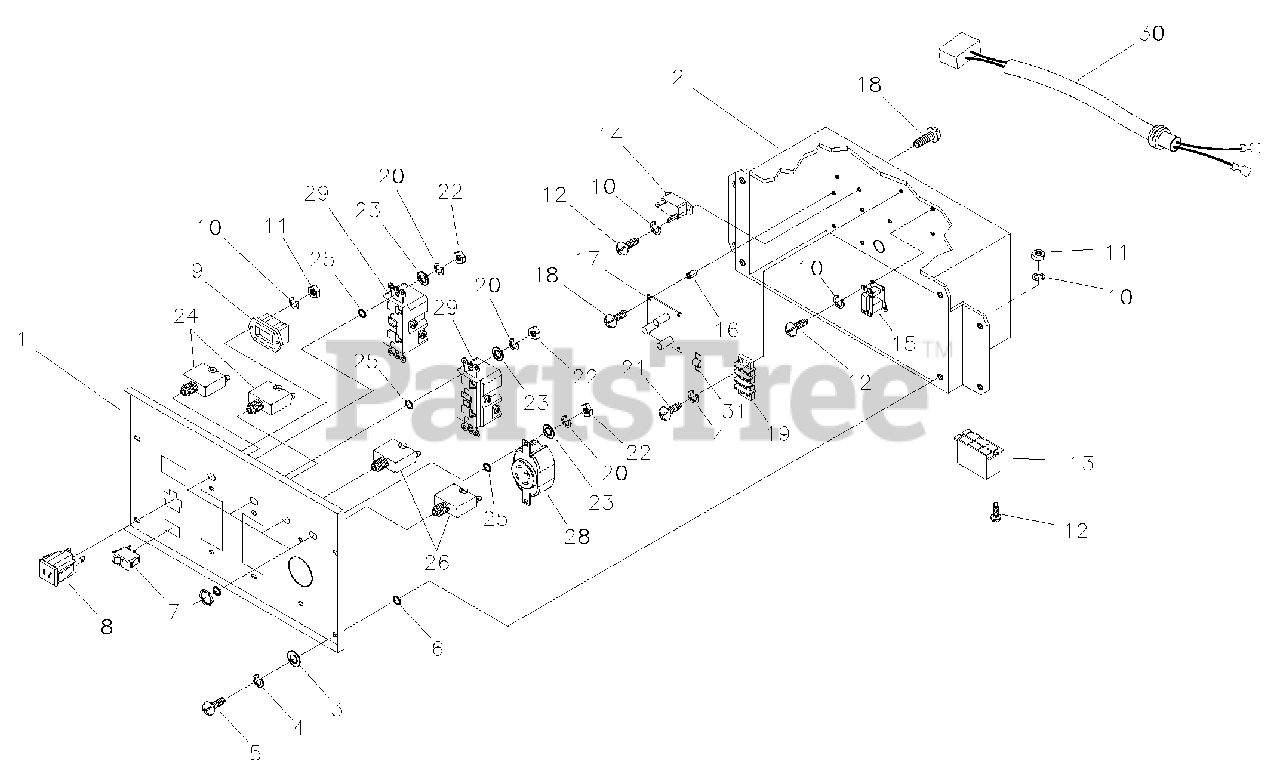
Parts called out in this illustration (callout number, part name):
1	PANEL, Control
2	BOX, Control Panel
4	WASHER, Lock
7	SWITCH, Rocker
8	OUTLET, 12VDC, Snap
9	METER, Hour
10	WASHER, Lock
13	HOUSING, Receptacle
14	BREAKER, Circuit
15	TRANSFORMER, Idle Cnt
16	STANDOFF, Hex
17	PCB, Idle Control
19	STRIP,Terminal
20	WASHER, Lock
24	BREAKER, Circuit
26	BREAKER, Circuit
27	JUMPER,Terminal Block
28	OUTLET, 120/240V, 30A
29	OUTLET, 120V, 20A, Duplex. GFCI
30	HARNESS,Wire
